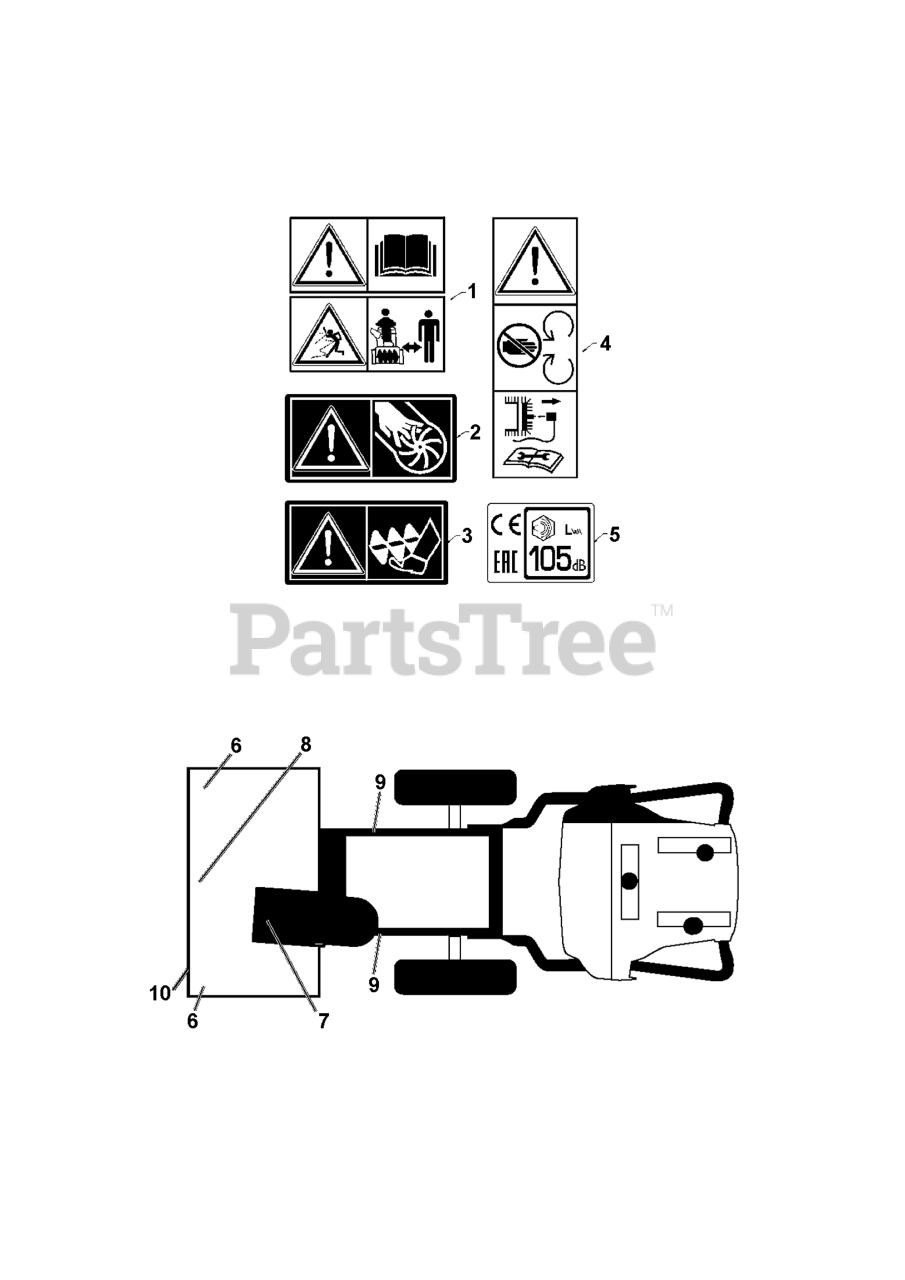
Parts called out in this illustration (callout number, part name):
1	DECAL.AUGER."
2	DECAL.CHUTE.SAFETY.EU/SC.17
3	DECAL.AUGER.SAFETY.
4	DECAL.BELT.GUARD.
5	DECAL.NOISE.LEV.105/CE.EAC.UKR
6	DECAL.AUGER.SAFETY.
7	DECAL.CHUTE.SAFETY.EU/SC.17
8	DECAL.AUGER."
9	DECAL.BELT.GUARD.
10	DECAL SNOW BUCKET TRIM GRAPHIC
